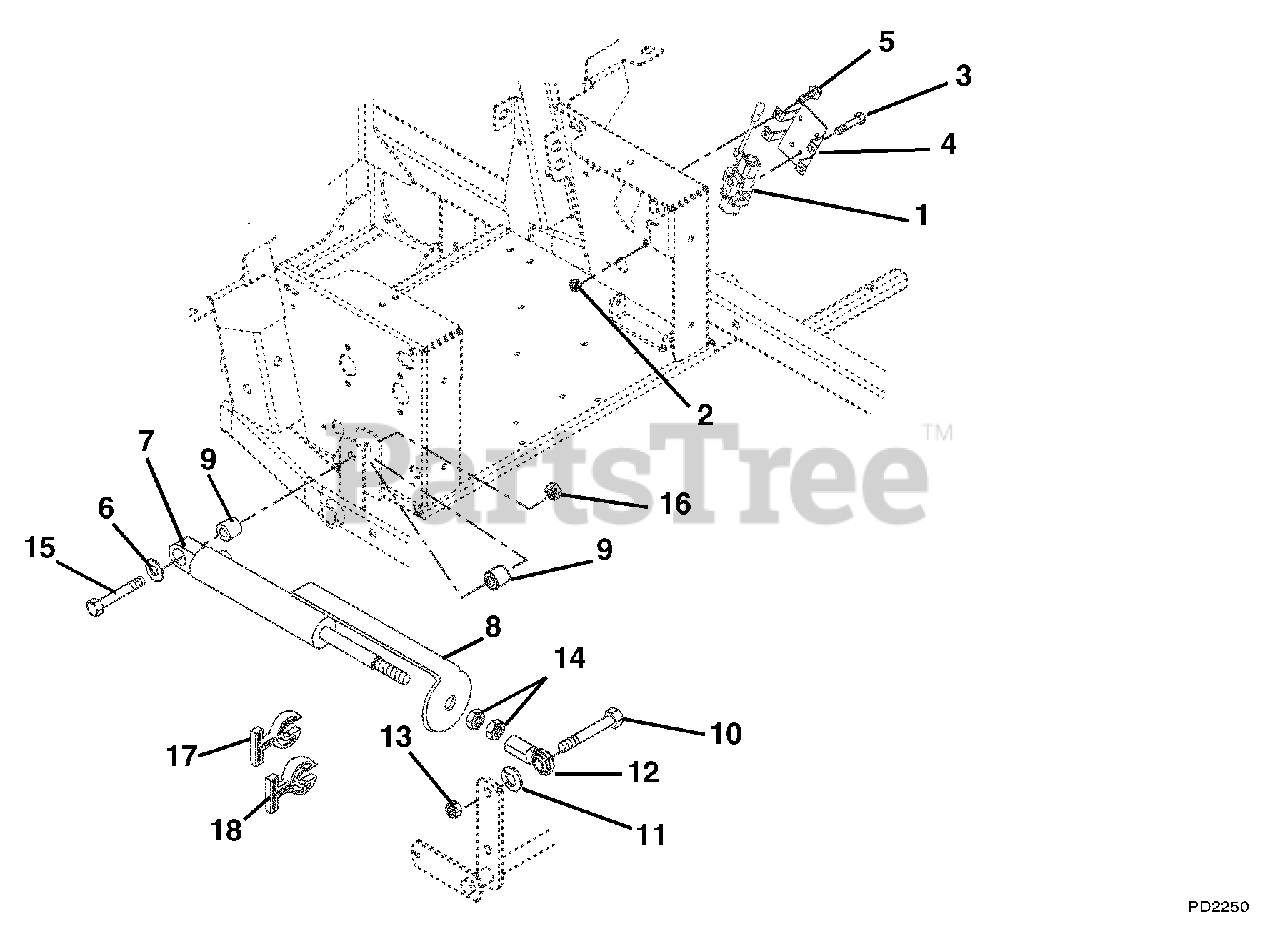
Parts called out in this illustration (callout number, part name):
1	Valve, Hydraulic
2	Nut-Locking-Nylon .31-18
3	Bolt-Hex .31-18 x 2.25 Grade 5
4	Bracket, Valve Mounting
5	Screw-Tapping .38-16 x .50 Hex Washer Head
6	Washer-Flat-Steel .515 x 1.625 x .25
7	Cylinder-Hydraulic Lift
8	Strap-Height of Cut Indicator
9	Bushing .516 x 1.00 x 1.05
10	Bolt-Hex .62-11 x 2.25 Grade 8
11	Washer-Lock .62 x .156
12	Rod End-Right Hand-Female .625
13	Nut-Locking-Center .62-11
14	Nut-Jam .625-18
15	Post, Cylinder Stop
16	Nut-Locking-Center .50-13
17	Stop, Cylinder .34 Thick
18	Stop, Cylinder .68 Thick
